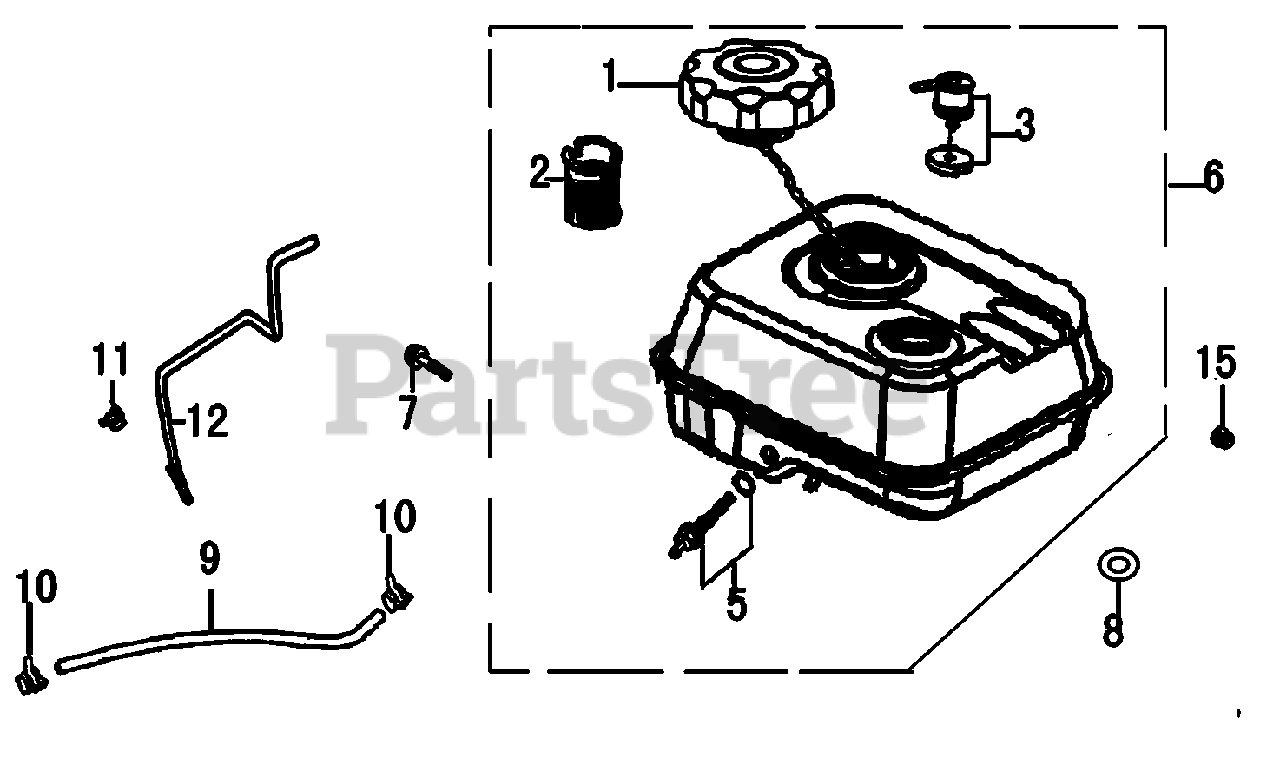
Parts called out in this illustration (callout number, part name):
1	CAP FUEL FILLER
2	FILTER, FUEL
3	ROLL OVER VALVE
5	JOINT ASSY., FUEL TANK
6	FUEL TANK ASSY W/ ROV
7	BOLT, FLANGE , 6X25
8	WASHER, RUBBER
9	HOSE, FUEL
12	HOSE, FORMED
15	NUT, FLANGE
